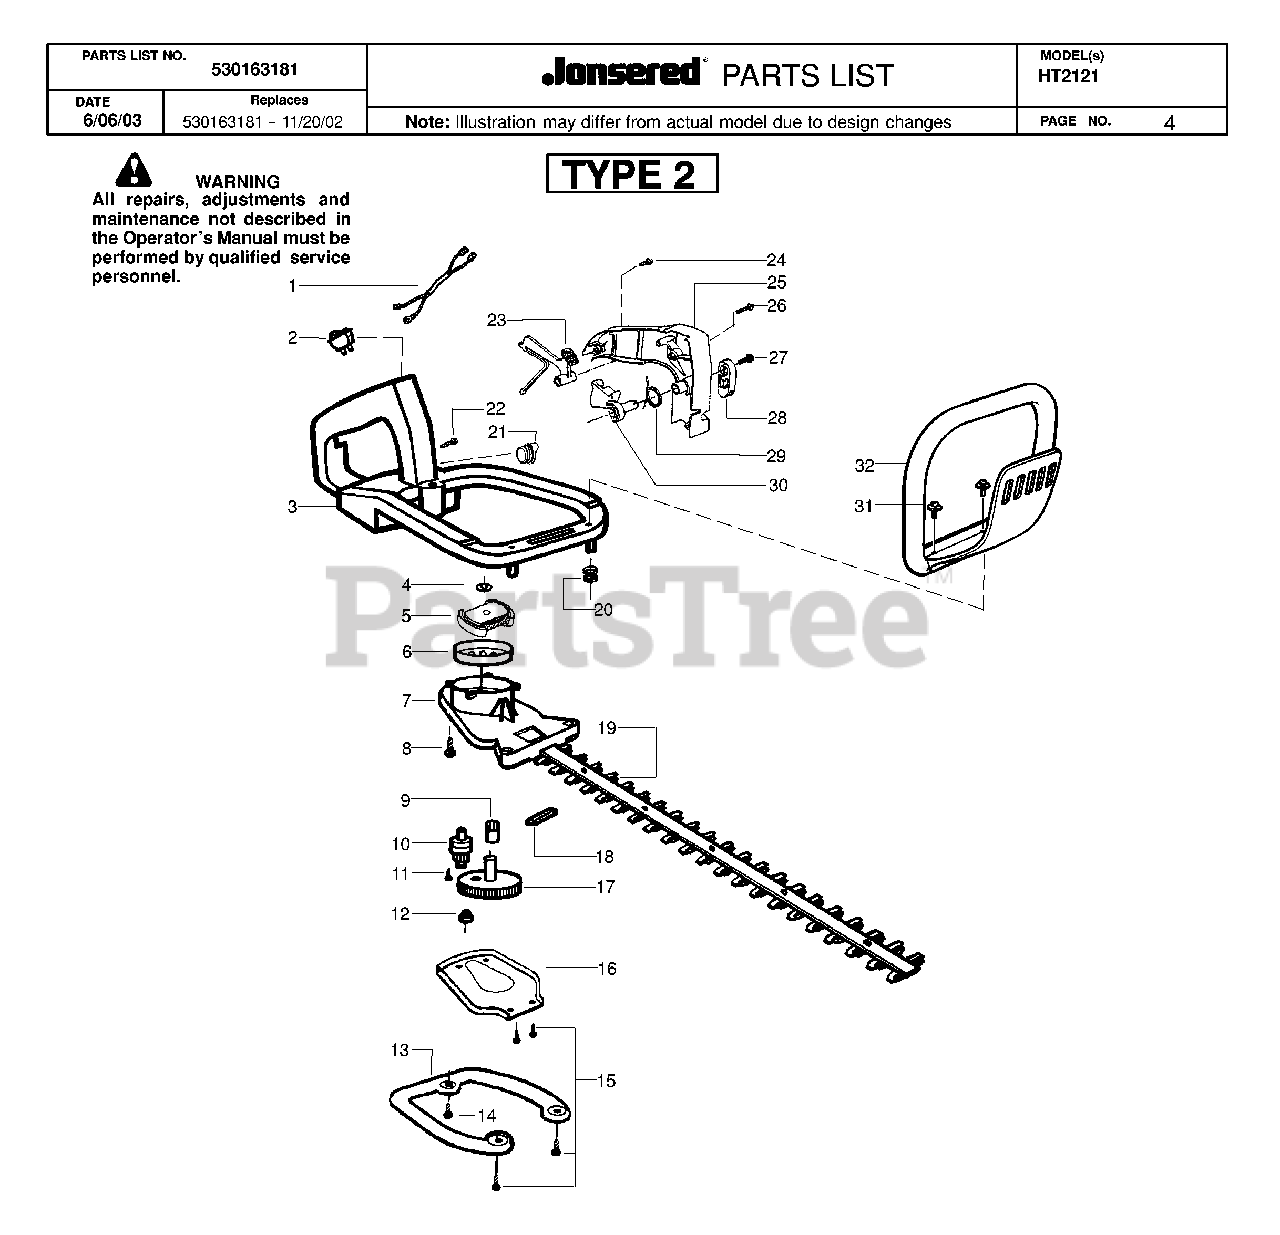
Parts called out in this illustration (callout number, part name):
3	HANDLE
4	WASHER FLAT
6	CLUTCH DRUM
7	GEAR HOUSING
8	SCREW-10-14 X 13/16 (PL
11	SCREW-10-16 X 1/2, TYPE 2
12	BLADE BUSHING
13	ISOLATOR PLATE
16	PLATE-GEARBOX COVER
19	BLADE ASSEMBLY
20	ANTIVIBE MOUNT
21	FUEL CAP
22	SCREW-10-16 X 1-3/8 PLA
23	LOCKOUT-THROTTLE
27	SCREW 8-16 X 9/16 (PLAS
